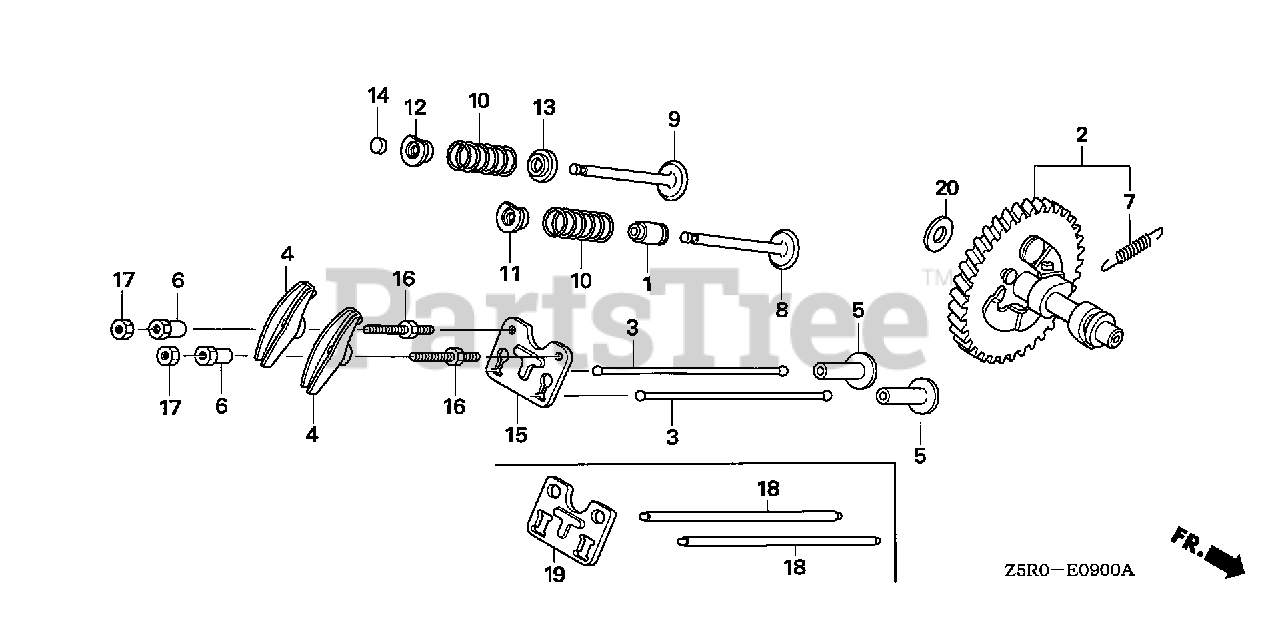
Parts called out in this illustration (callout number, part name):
1	SEAL, VALVE STEM
2	CAMSHAFT ASSY.
4	ARM, VALVE ROCKER
5	LIFTER, VALVE
6	PIVOT, ROCKER ARM
7	SPRING, WEIGHT RETURN
8	VALVE, IN.
9	VALVE, EX.
10	SPRING, VALVE
11	RETAINER, IN. VALVE SPRING
12	RETAINER, EX. VALVE SPRING
13	SEAT, VALVE SPRING
14	ROTATOR, VALVE
15	GUIDE, PUSH ROD
16	BOLT, PIVOT (8MM)
17	NUT, PIVOT ADJUSTING
